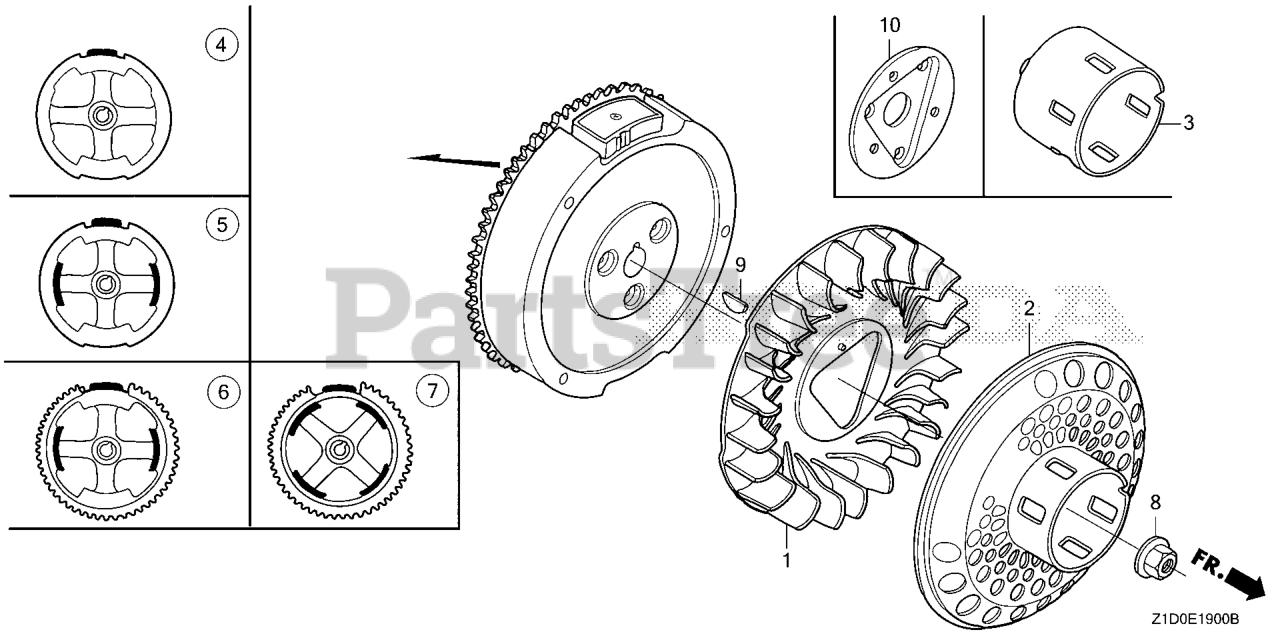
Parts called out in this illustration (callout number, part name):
1	FAN, COOLING
3	PULLEY, STARTER
8	NUT, SPECIAL (16MM) (1)
9	KEY, SPECIAL WOODRUFF (25X18)
